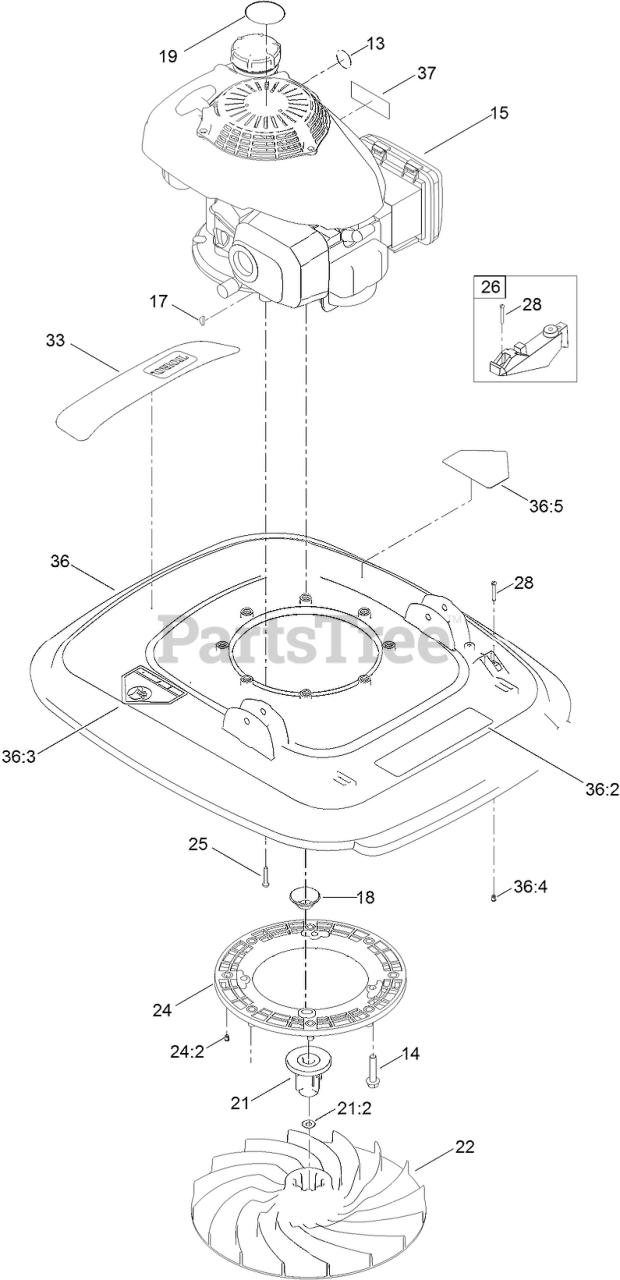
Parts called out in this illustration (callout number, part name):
13	DECAL
14	SCREW-TAPTITE
15	ENGINE-HONDA
17	KEY-WOODRUFF
18	PROTECTOR-SEAL, OIL
19	DECAL-ENGINE
21	DRIVE AND SPACER ASM
21:2	WASHER-PLAIN
22	IMPELLER
24	FRAME-ENGINE
24:2	INSERT-BRASS
25	SET-SCREW
26	BRACKET
28	SCREW
33	DECAL-HOVER PRO
36	KIT - DECK 21" ASM 02611
36:2	DECAL-WARNING
36:3	DECAL-DANGER
36:4	INSERT
36:5	DECAL-DANGER
37	DECAL-ARRESTOR, SPARK
